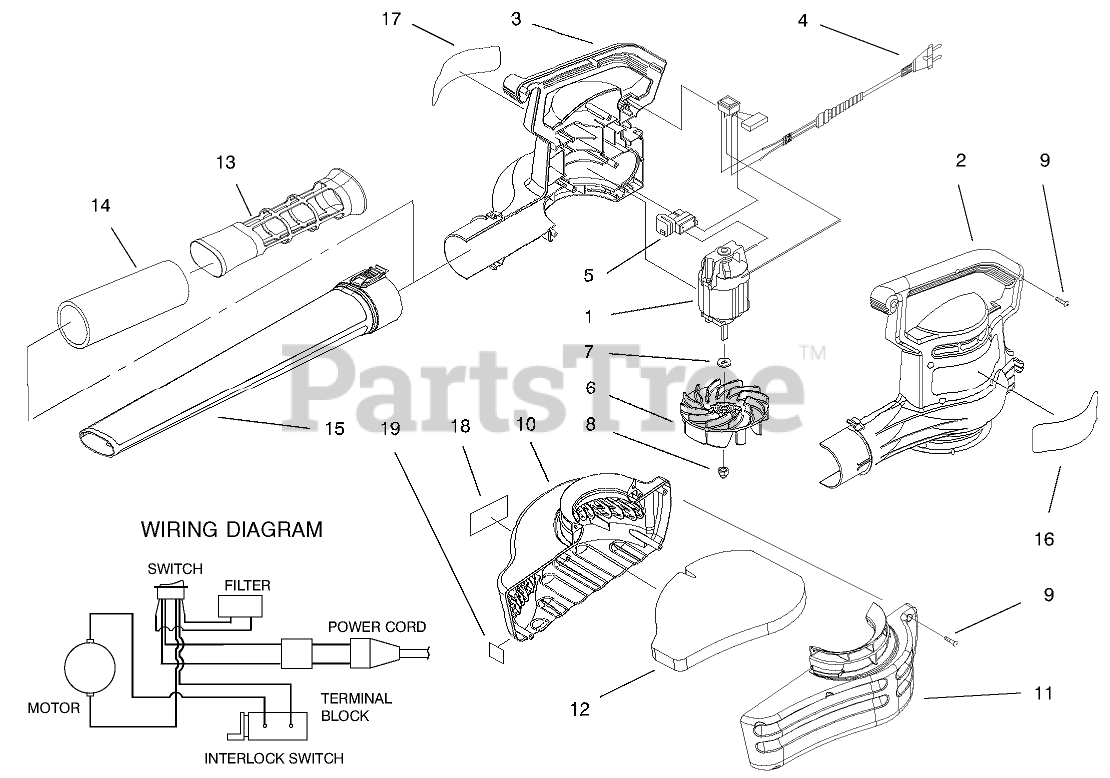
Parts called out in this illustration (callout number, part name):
1	MOTOR - 2.25" STACK 230V
2	Housing-L.H.
3	Housing-R.H.
4	HARNESS - BLOWER, 230 VOL
5	SWITCH - INTERLOCK
6	IMPELLER - BLOWER
7	WASHER
8	NUT - IMPELLER
9	SCREW-PPH
10	INLET - QUIET, RH
11	INLET - QUIET, LH
12	FOAM - INLET
13	INSERT - QUIET
14	FOAM - INSERT
15	TUBE-BLOWER LONG
16	DECAL, LOGO, SUPRBLWR
17	Decal-Warning
18	DECAL - QUIETECH
19	DECAL - 63DBA
